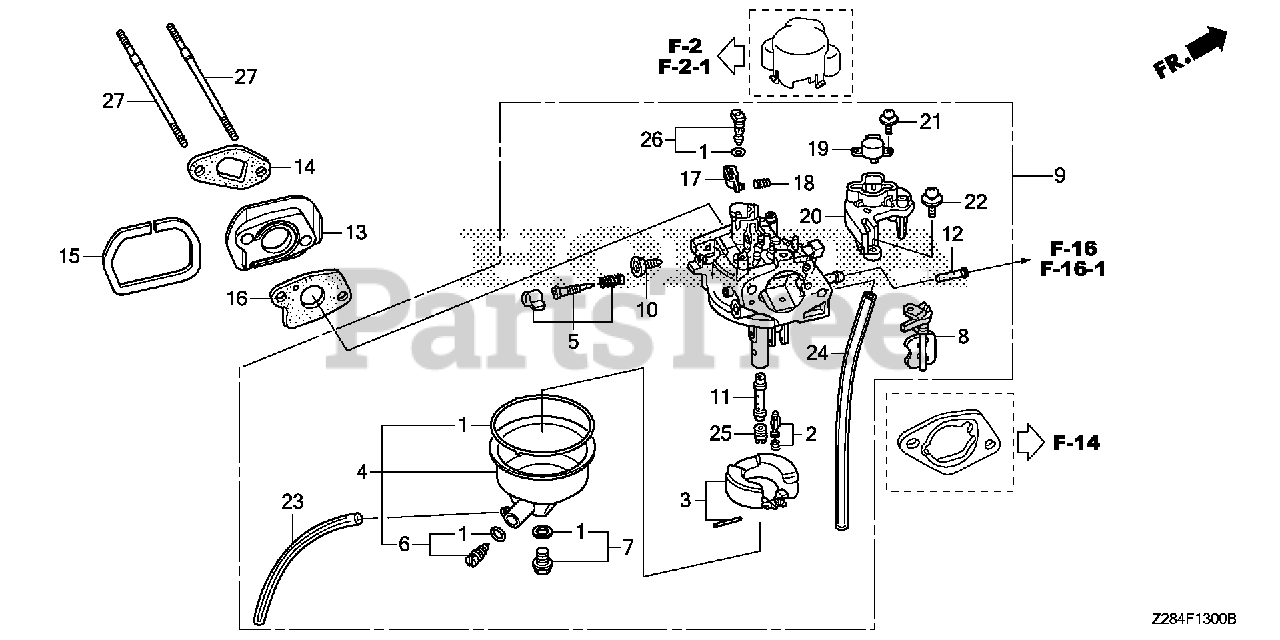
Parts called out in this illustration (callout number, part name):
1	GASKET SET
2	VALVE SET, FLOAT (SEAT NOT INCLUDED)
4	CHAMBER SET, FLOAT
5	SCREW SET, PILOT
6	SCREW SET, DRAIN
7	SCREW SET
9	CARBURETOR ASSY. (BE67S B)
10	SCREW, THROTTLE STOP
11	NOZZLE, MAIN
12	SCREEN, FUEL STRAINER
13	INSULATOR, CARBURETOR
14	GASKET, INSULATOR
15	SEAL, CARBURETOR INSULATOR
16	GASKET, CARBURETOR
17	LEVER, LINK
18	SPRING, COMPRESSION COIL
19	MOTOR, THROTTLE CONTROL
20	BRACKET, THROTTLE MOTOR
21	SCREW-WASHER (3X8)
22	SCREW-WASHER (4X10)
23	BULK HOSE, VINYL (3.5X6.5X8000) (3.5X6.5X120)
24	BULK HOSE, VINYL (4X7X8000) (4X7X220)
25	JET, MAIN (#72)
25	JET, MAIN (#75)
25	JET, MAIN (#78)
26	JET SET, PILOT (#45)
27	BOLT, STUD (6X108) (CT200)
